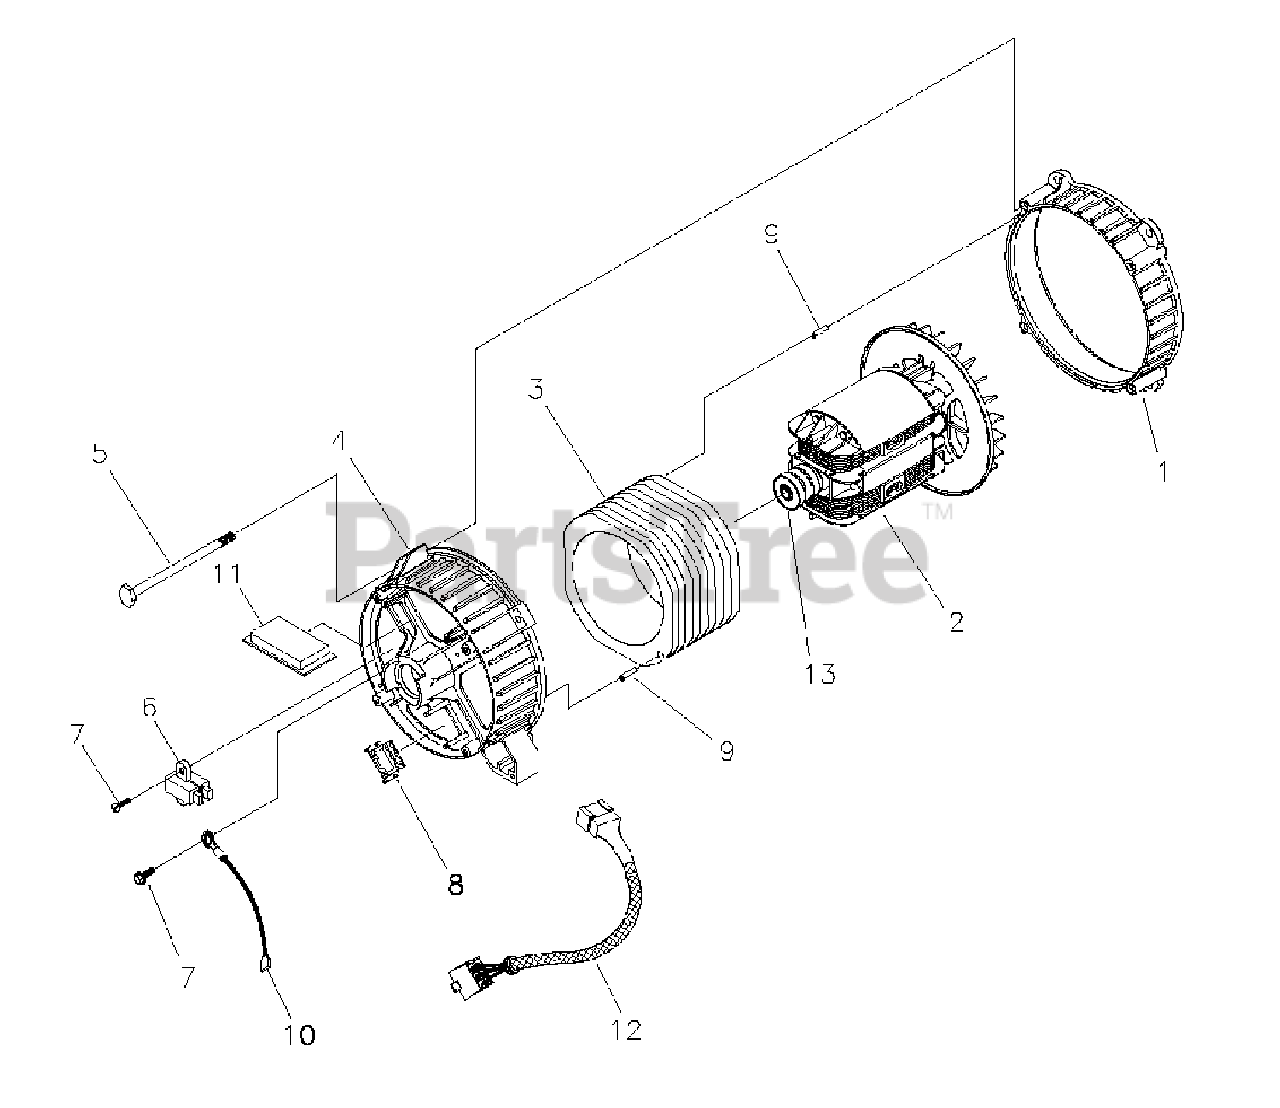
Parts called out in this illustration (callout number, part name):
1	ADAPTER, Mounting, Alternator
4	RBC, (with O-Ring, p/n 189197GS)
5	HHCS, M6 - 1.0 x 140 SEMS
6	ASSY, Holder, Brush
7	TAPTITE, M5 - 0.8 x 16
8	RECEPTACLE, 6 pin
9	PIN, Roll, 4mm x 10
10	ASSY, Wire, Ground
11	REGULATOR, Voltage, AVR
12	HARNESS, Wire, Power
13	BEARING
